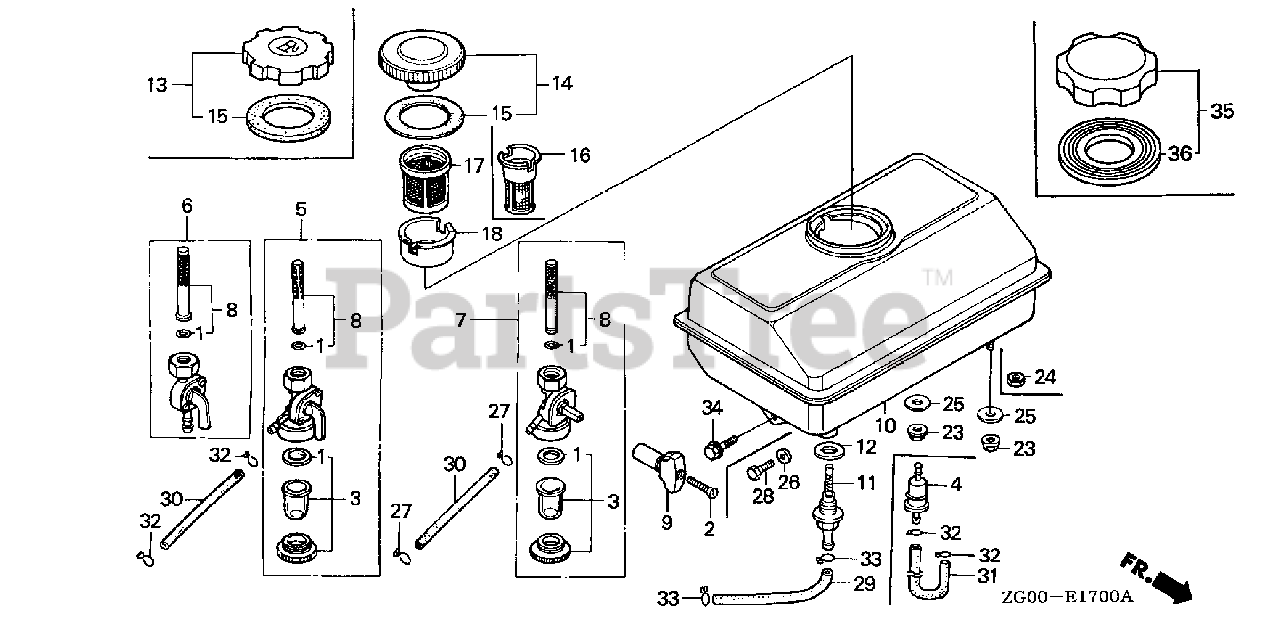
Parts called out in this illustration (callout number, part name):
10	TANK, FUEL *NH31* (MCKINLEY WHITE)
11	JOINT, FUEL TANK
12	O-RING (13.5X1.5) (ARAI)
13	CAP, FUEL FILLER
14	CAP, FUEL FILLER
15	GASKET, FUEL FILLER CAP
16	FILTER, FUEL
23	NUT, FLANGE (6MM)
29	BULK HOSE, FUEL (4.5X3000) (4.5X55)
33	CLIP, TUBE (B8)
34	BOLT, FLANGE (6X14)
